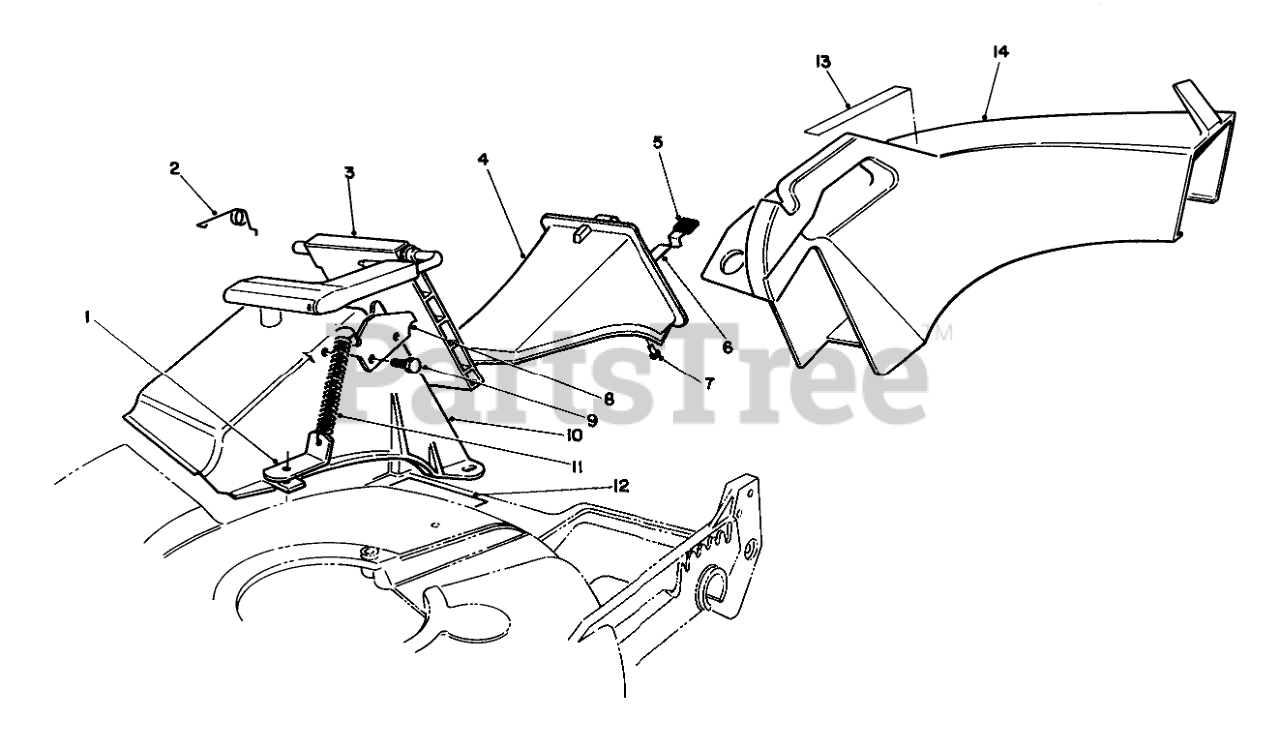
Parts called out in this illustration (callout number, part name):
1	Bracket-Spring
2	RETAINER-DOOR
3	DOOR ASSEMBLY
4	Plug Assembly (Incl. Ref. #5-7)
5	GRIP-LATCH
6	LATCH-PLUG, DISCHARGE
7	RIVET-HEAD, FLAT
8	DOOR LATCH PLATE
9	SCREW-PLASTITE
10	DISCHARGE TUNNEL
11	SPRING-DOOR
12	DECAL - CAUTION
13	DECAL - WARNING
14	CHUTE
